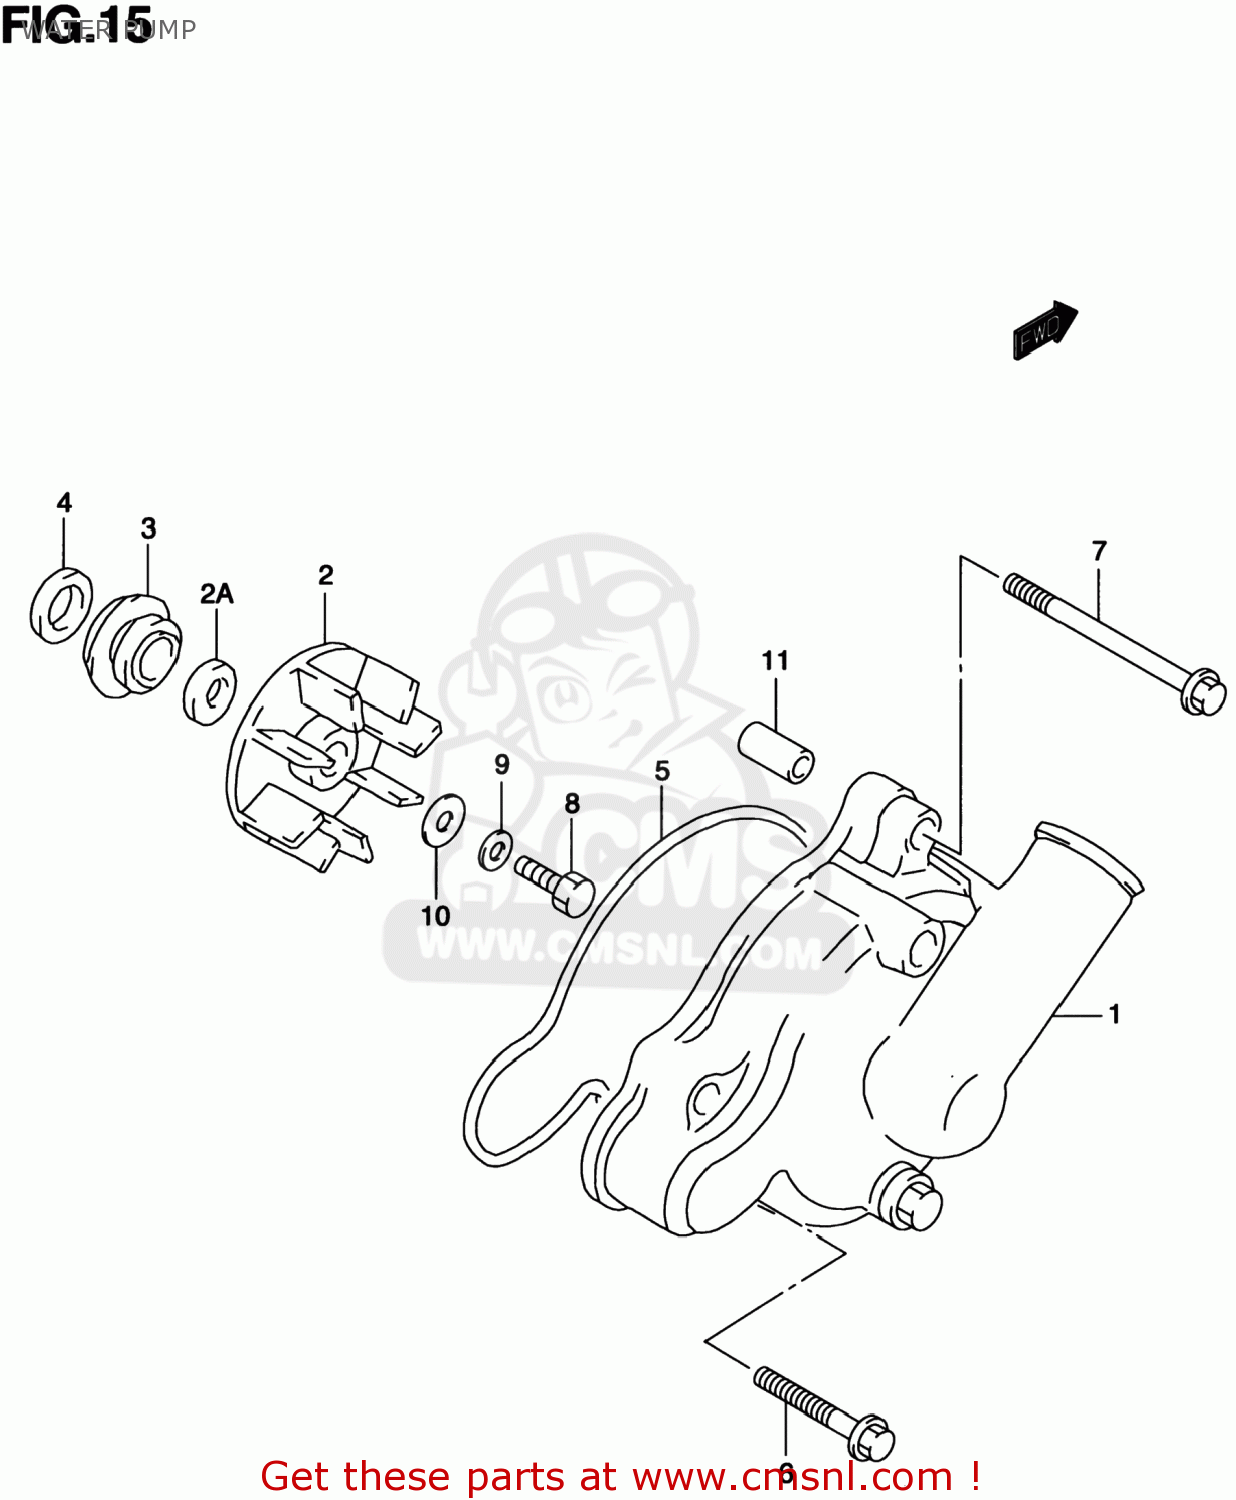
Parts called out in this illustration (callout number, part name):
1	CASE,WATER PUMP
2	IMPELLER,WATER PUMP
2A	WASHER,IMPELLER
3	SEAL,MECHANICAL
4	SEAL,WATER PUMP SHAFT OIL
5	O RING,WATER PUMP CASE
6	BOLT
7	BOLT
8	BOLT(6X13)
9	WASHER
10	GASKET(6X15X2.2) (NAS)
11	PIN
